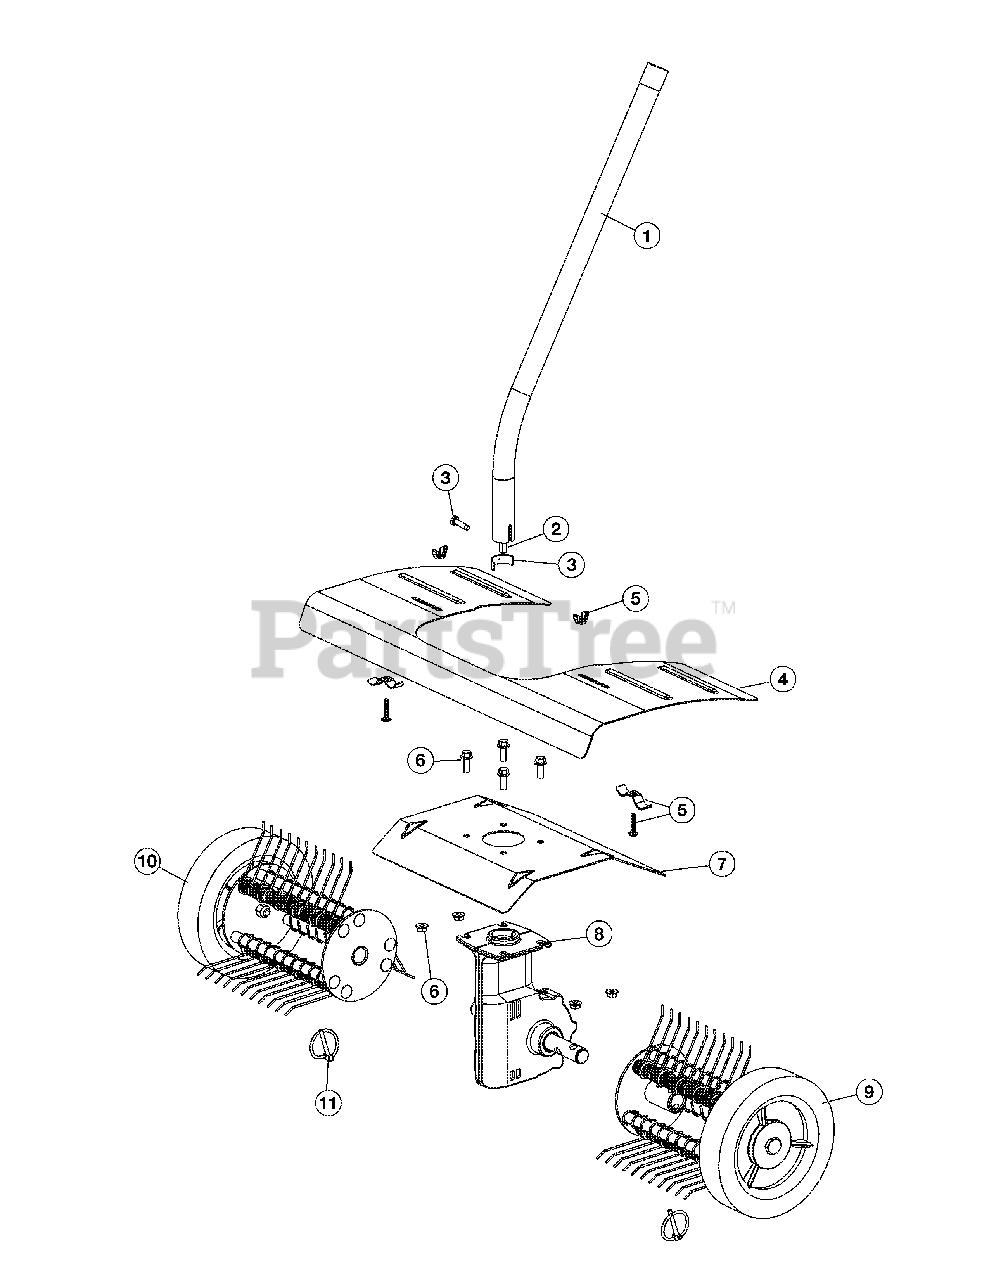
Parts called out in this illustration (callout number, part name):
1	Drive Shaft Housing Assembly
2	Flexible Drive Shaft
3	Retainer Sleeve w/ Bolt
4	Dethatcher Guard Assembly
5	Dethatcher Guard Mounting Hardware
6	Guard Mounting Hardware
7	Guard
8	Gearbox Assembly
9	Dethatcher Assembly
10	Dethatcher Assembly
11	Click Pin
